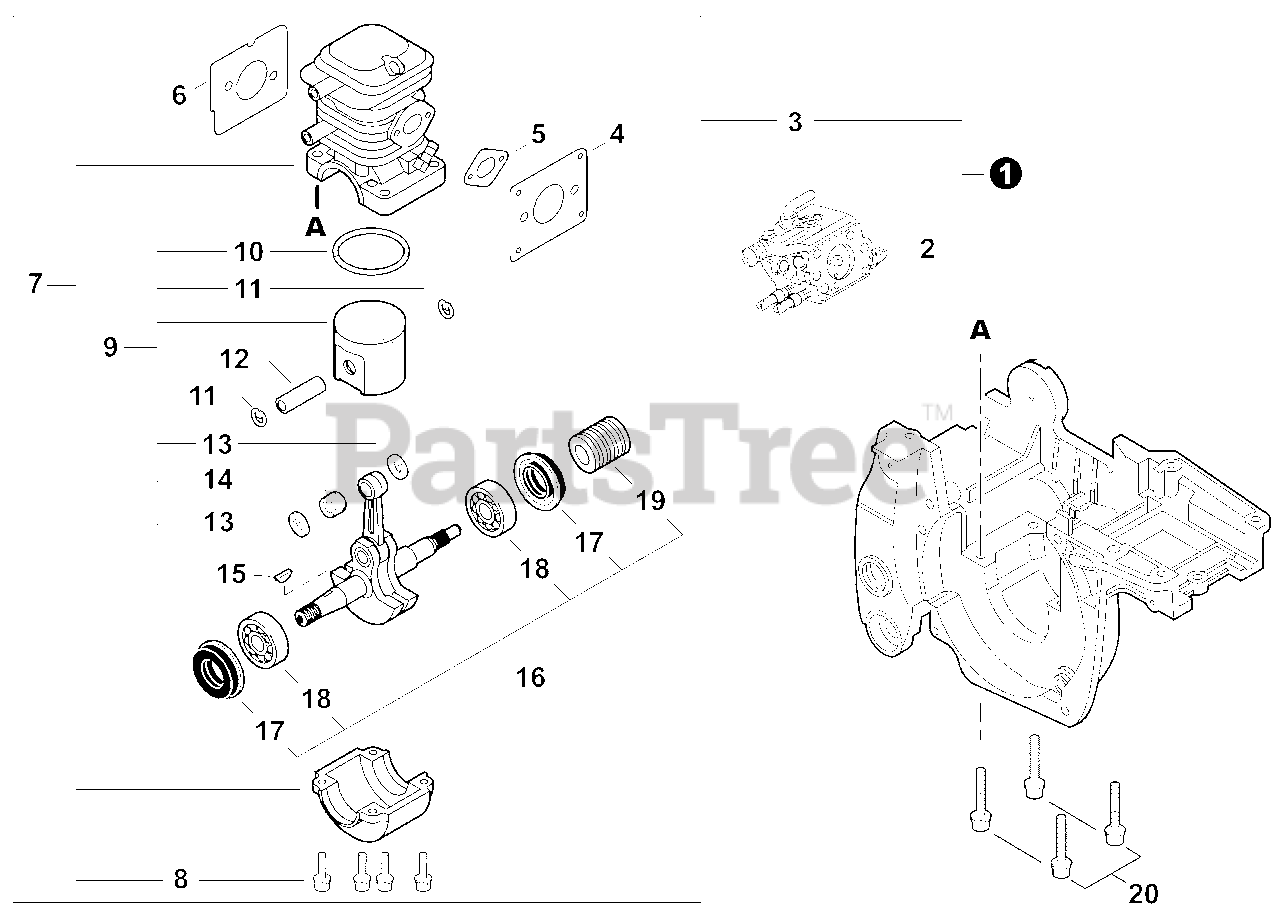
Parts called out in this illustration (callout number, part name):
1	SHORT BLOCK AND CARBURETOR WT-981
2	CARBURETOR WT-981
3	SHORT BLOCK
4	GASKET, INTAKE
5	GASKET, INTAKE
6	GASKET, EXHAUST
7	CRANKCASE SET
8	BOLT 5×22
9	PISTON KIT
10	RING, PISTON
11	RING, SNAP
12	PIN, PISTON 6×9×30
13	WASHER, THRUST 9×12×15×3
14	BEARING, NEEDLE 9
15	KEY, WOODRUFF
16	CRANKSHAFT ASSY
17	SEAL, OIL 12
18	BEARING, BALL 6201
19	GEAR, WORM
20	BOLT 5×30
